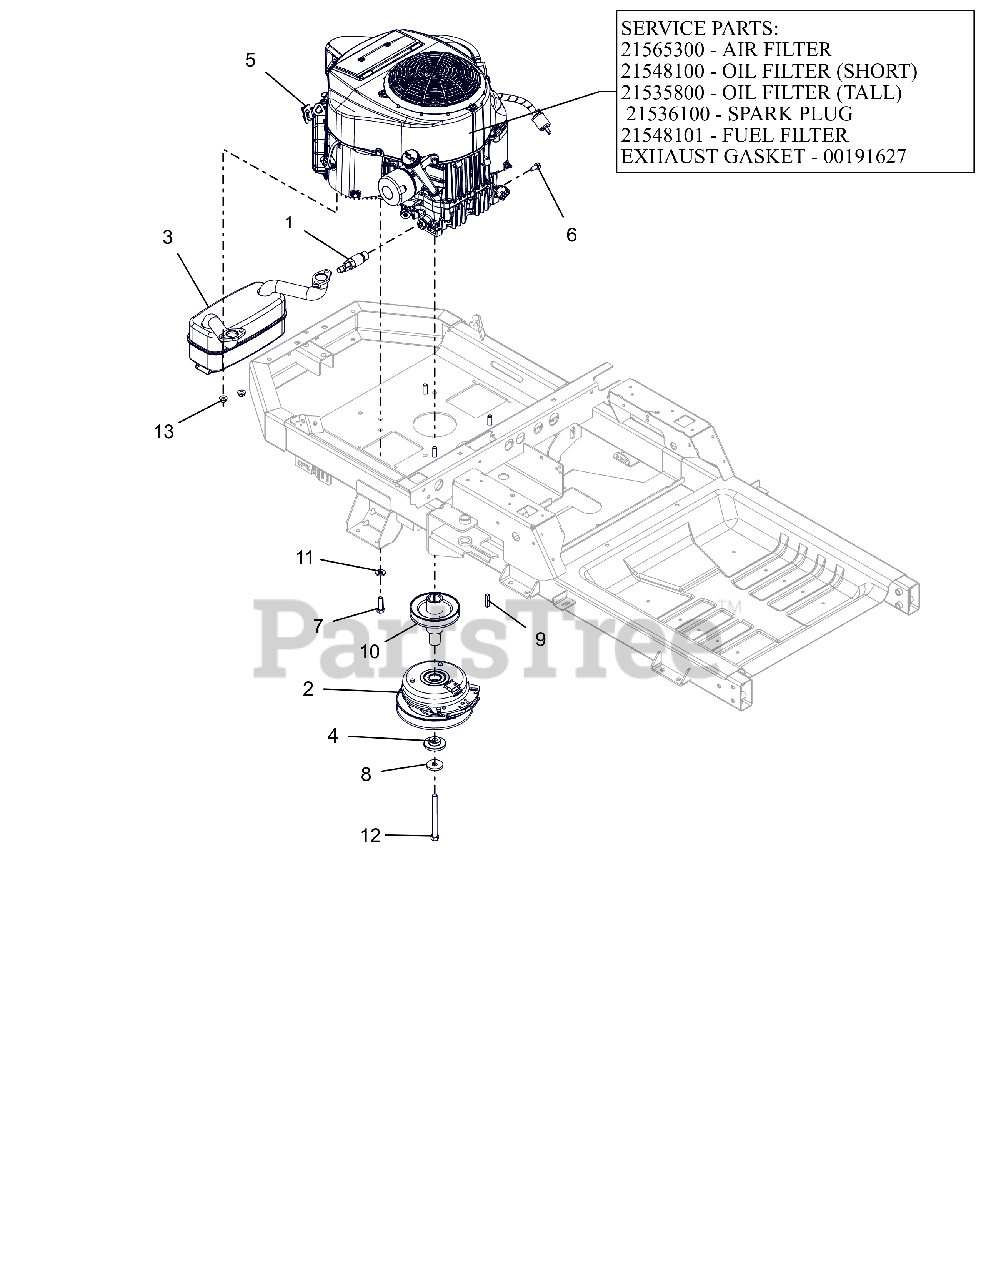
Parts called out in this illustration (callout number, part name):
1	DRAIN, OIL M20X2.5
2	CLUTCH,105FTLB MONOPOLE 6.83"
3	MUFFLER - KAWASAKI
4	BSHG-FLG .469X1.06X.574X2.0
5	ENGINE, KAWASAKI FR600
5	AIR FILTER, KAWASAKI FR
5	OIL FILTER, KAWASAKI FR
5	FILTER,OIL - KAW
5	PLUG, SPARK
5	FUEL FILTER-KAWASAKI FR
5	GASKET, MUFFLER S/O
6	BLT, HEX M8-1.25X20 G8.8 ZCC
7	BLT, HEX .38-16X1.25 G5 ZCC NT
8	WASHER, 7/16" SPRING DISK
9	KEY-SQ .25 X 1.25 X .25 SAE
10	WLDMT, DRIVE SHEAVE-X
11	WASHER, 3/8" SPRING DISC
12	BLT, HEX .44-20X4.50 G8 ZCC NT
13	NUT-LK-TOP-FLG M8 ZCC
